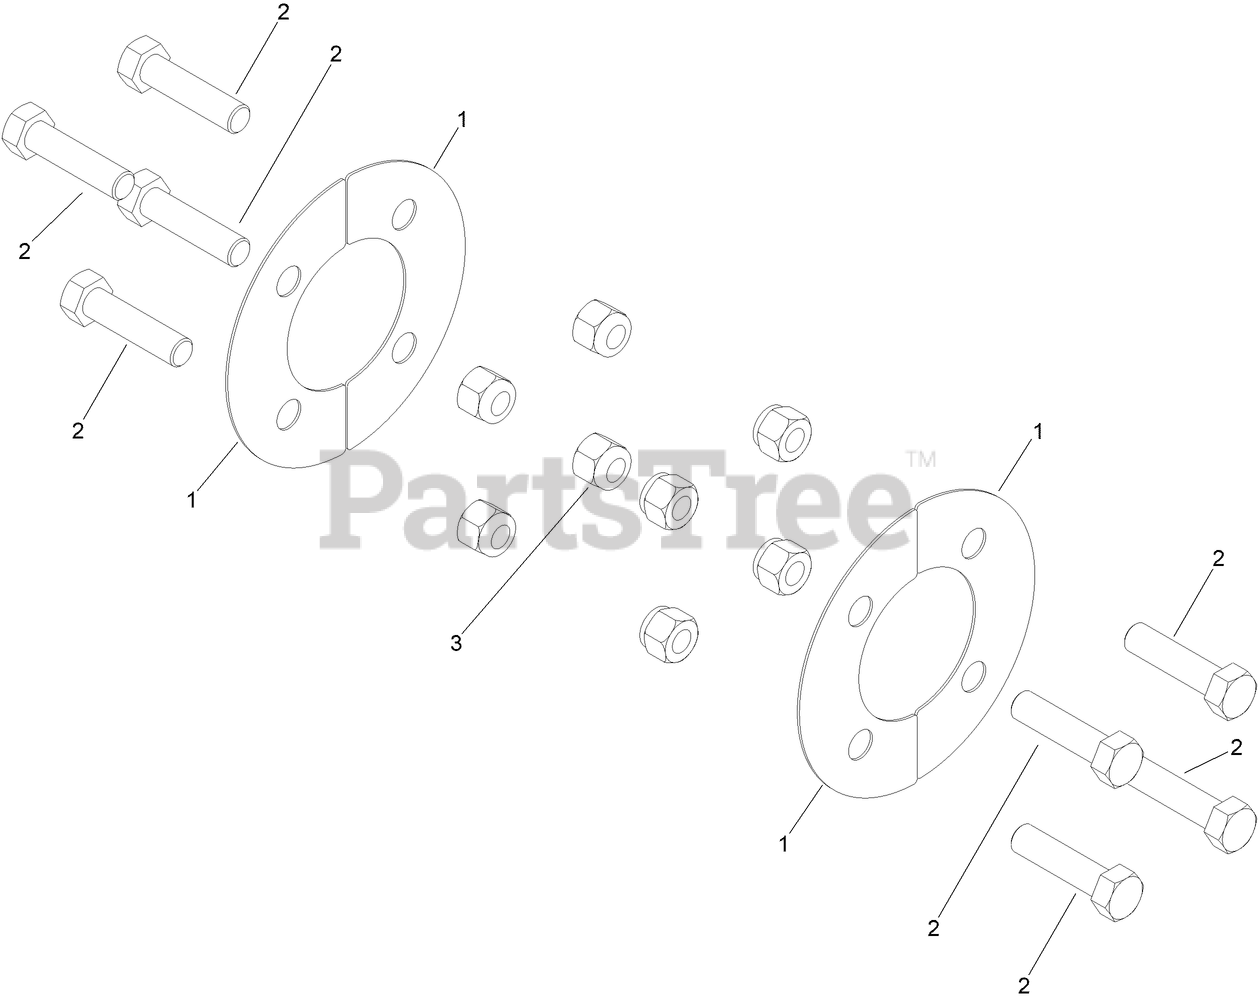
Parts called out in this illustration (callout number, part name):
1	PLATE-SHIM,HUB
2	SCREW-HH
3	NUT-LOCK
